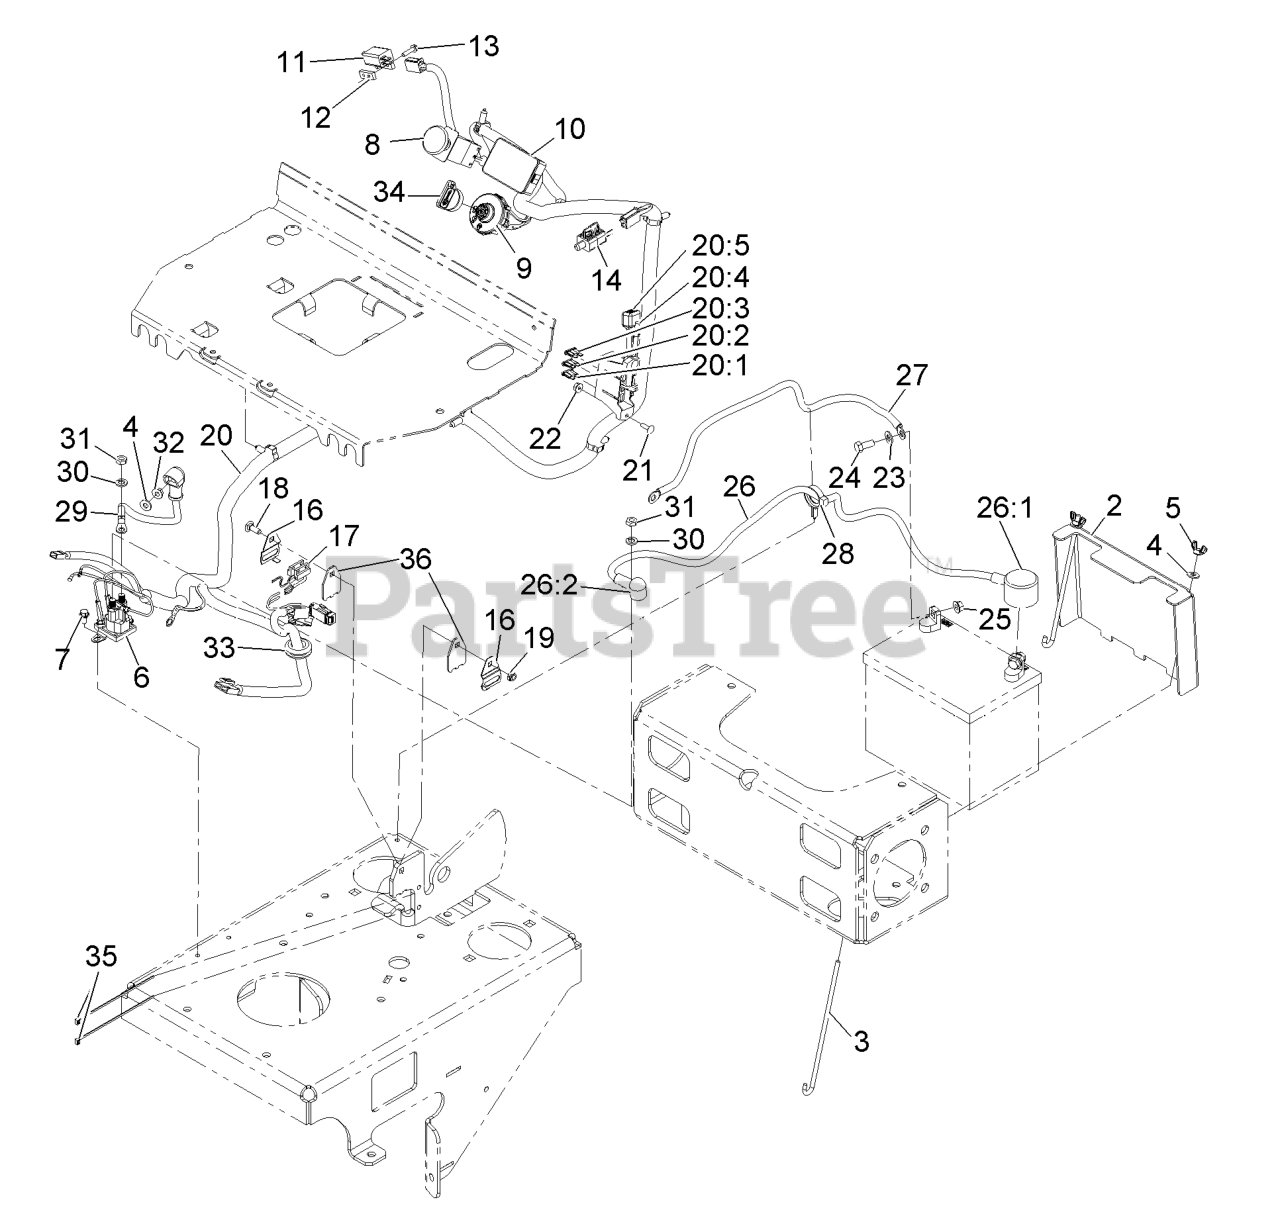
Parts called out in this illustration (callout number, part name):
2	COVER-BATTERY
3	BOLT-HOLDDOWN
4	WASHER-FLAT
5	WINGNUT
6	SOLENOID
7	SCREW-HWH
8	SWITCH-PTO, ON-ON
10	MODULE-HOUR METER
11	SWITCH-CLOSED, NORMALLY
12	PLATE-TAPPED
13	SCREW-HWH
14	SWITCH-PLUNGER, NC, SPST
16	CLAMP-SWITCH
17	HARNESS-SWITCH, REED
18	BOLT-CARR
19	NUT-LOCK, NI
20	HARNESS-WIRE
20:1	FUSE-BLADE, 30 AMP
20:2	FUSE-BLADE, 25 AMP
20:3	FUSE-BLADE, 10 AMP
20:4	CAP-PLUG
21	SCREW-CARR
23	WASHER-PLAIN
24	SCREW-HH
25	NUT-HHF, SMOOTH
26	ASM,POSITIVE BATTERY CABL
26:1	INSULATOR-BATTERY
26:2	INSULATOR-SOLENOID
27	CABLE-BATTERY, NEGATIVE
28	CLAMP-HOSE
29	CABLE-BATTERY, RED
30	WASHER-LOCK
31	NUT-JAM
33	GROMMET
34	KEY-IGNITION
35	TIE-CABLE
36	PLATE-SPACER
